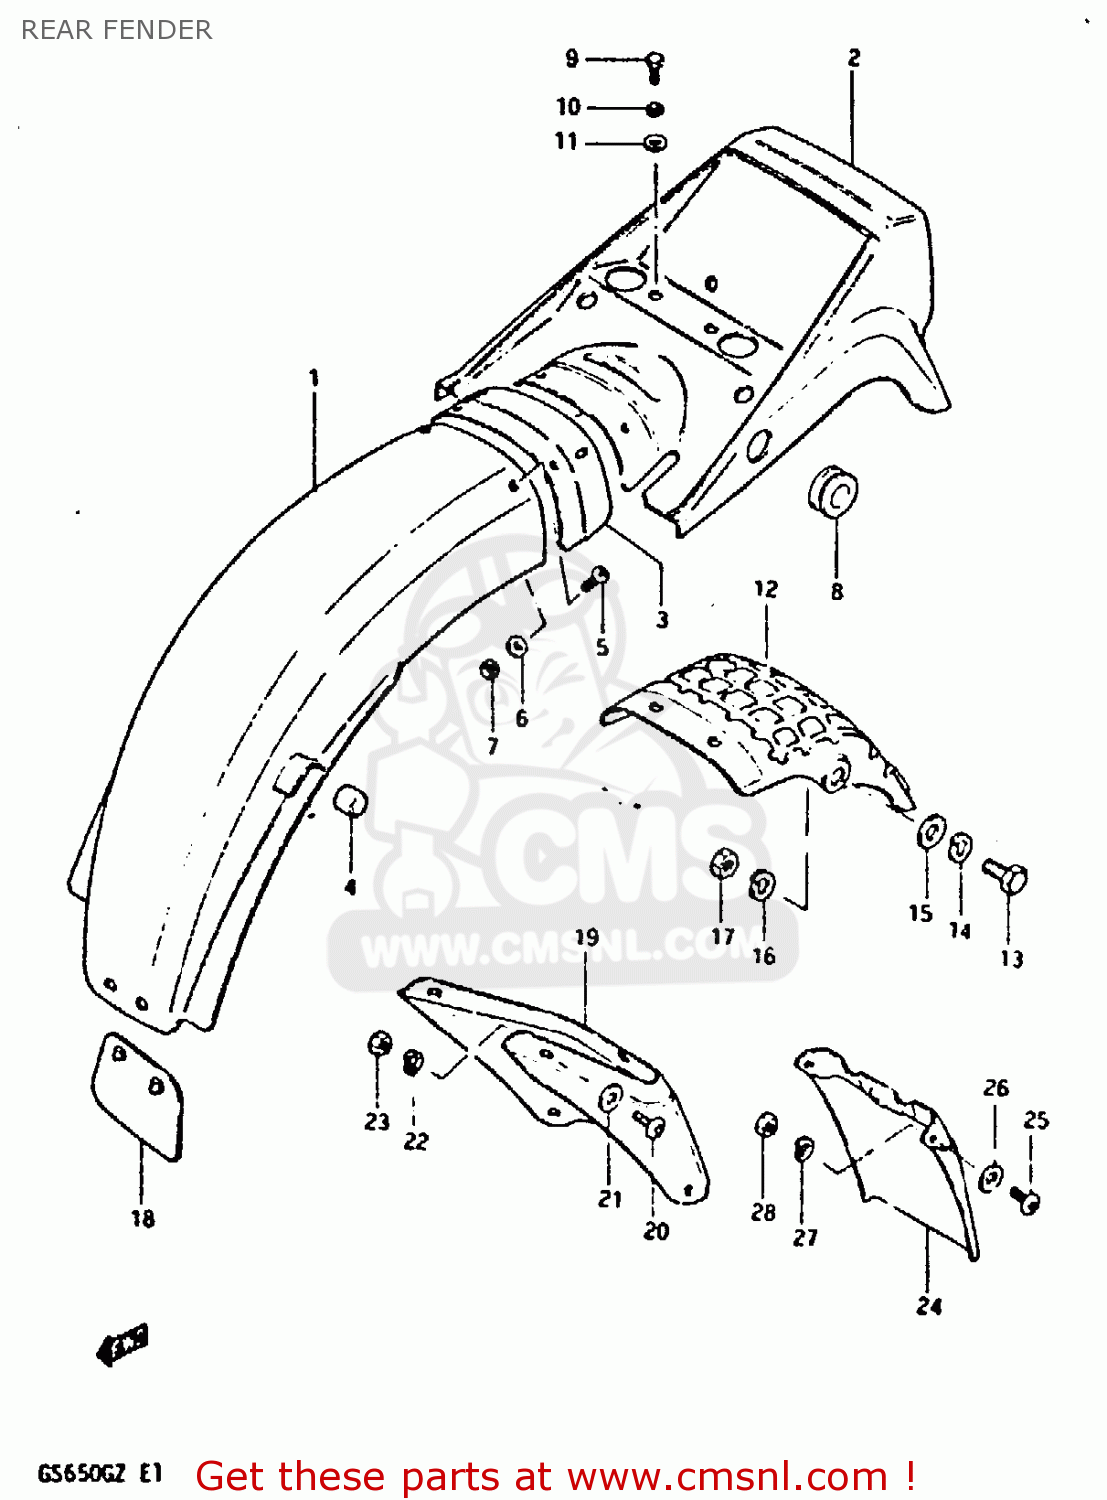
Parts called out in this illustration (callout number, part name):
1	BODY,REAR FENDER,REAR
2	BODY,REAR FENDER,REAR
3	JOINT,REAR FENDER
4	CUSHION
5	SCREW M5X12 DIN 7985/N
6	WASHER (5.5X16X1.2)
7	NUT
8	GROMMET,SEAT LOCK HOLE
9	BOLT
10	LOCK WASHER
11	WASHER
12	REINFORCEMENT,REAR FENDER
13	BOLT
14	LOCK WASHER
15	WASHER
16	LOCK WASHER
17	NUT
18	GUIDE,RR FENDER MUD
